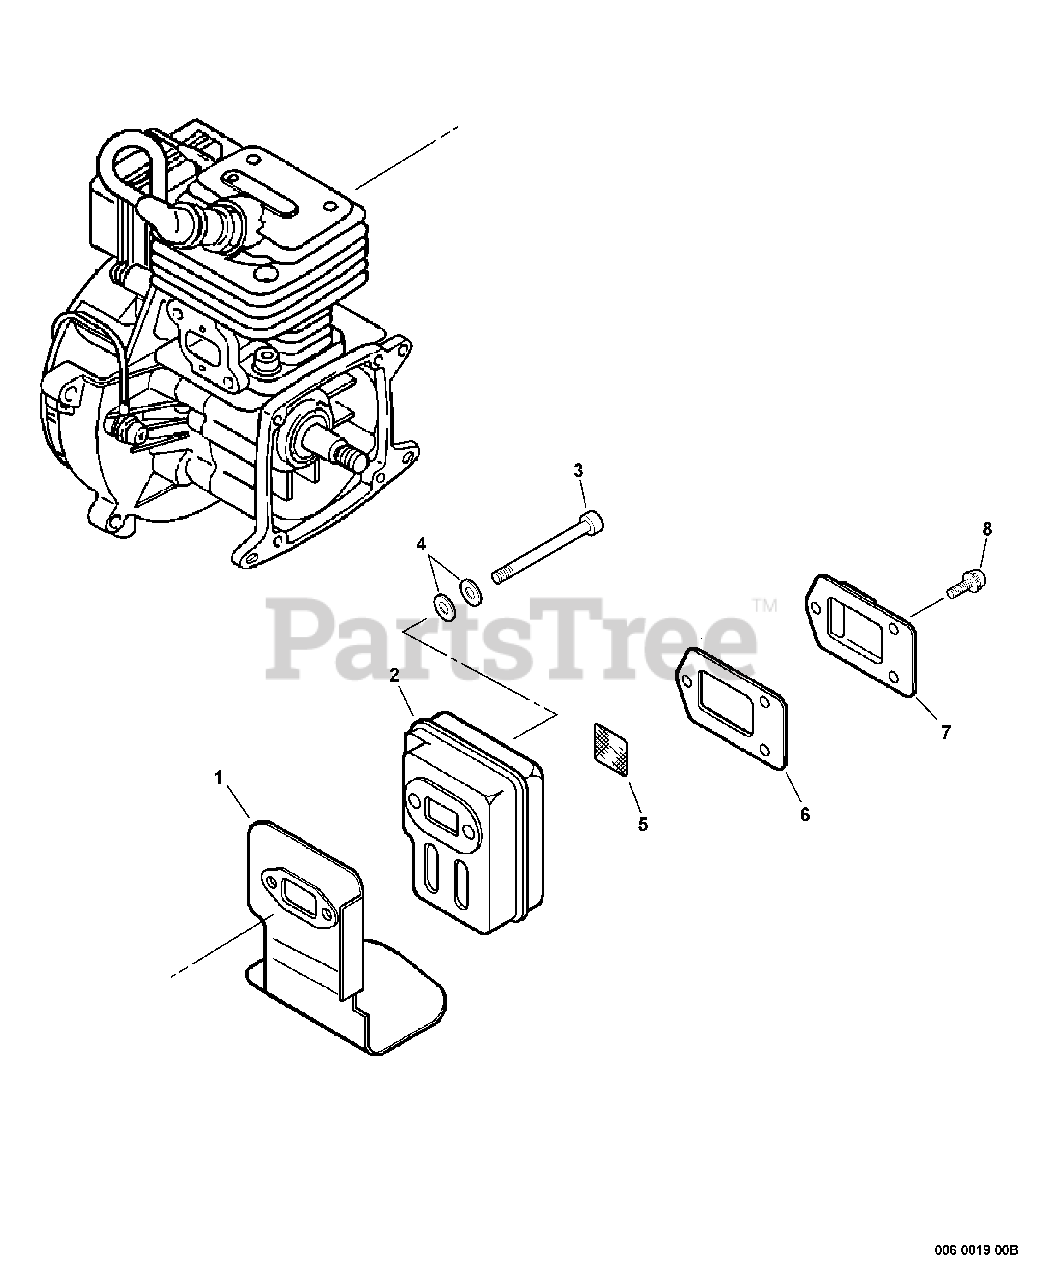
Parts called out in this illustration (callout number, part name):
1	HEAT SHIELD, EXHAUST
3	BOLT 5×55
4	WASHER, FLAT 5.5×10×0.8
5	SCREEN, SPARK ARRESTER
6	GASKET, EXHAUST
7	GUIDE, EXHAUST
8	SCREW 4×12
